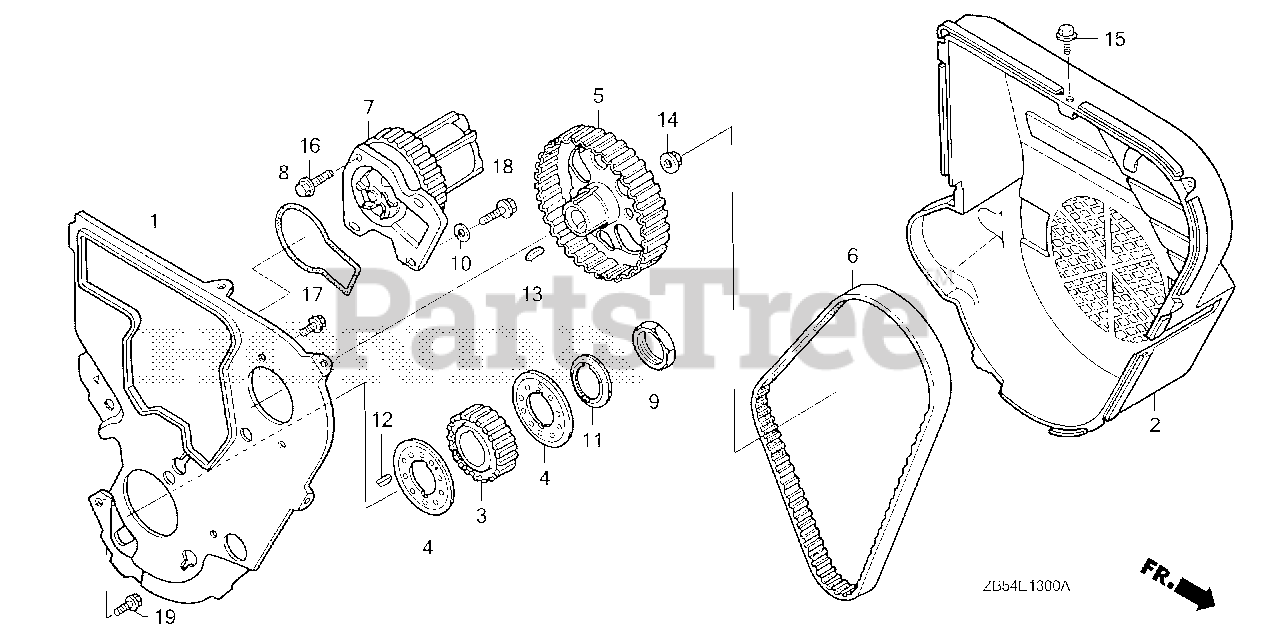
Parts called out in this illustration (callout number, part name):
1	COVER B, TIMING BELT
2	COVER A, TIMING BELT
3	PULLEY, TIMING
4	FLANGE, TIMING PULLEY
5	PULLEY, CAMSHAFT
6	BELT, TIMING
7	WATER PUMP
8	O-RING, WATER PUMP
9	NUT, LOCK (30MM)
10	WASHER, PLAIN (6.5X15)
11	WASHER, LOCK (30MM)
12	KEY, SPECIAL WOODRUFF (25X18)
13	KEY, WOODRUFF (16X12)
14	NUT, FLANGE (10MM)
15	BOLT, FLANGE (6X10)
16	BOLT, FLANGE (6X22)
17	BOLT, FLANGE (6X12)
18	BOLT, FLANGE (6X22)
19	BOLT, HEX. (6X10)
